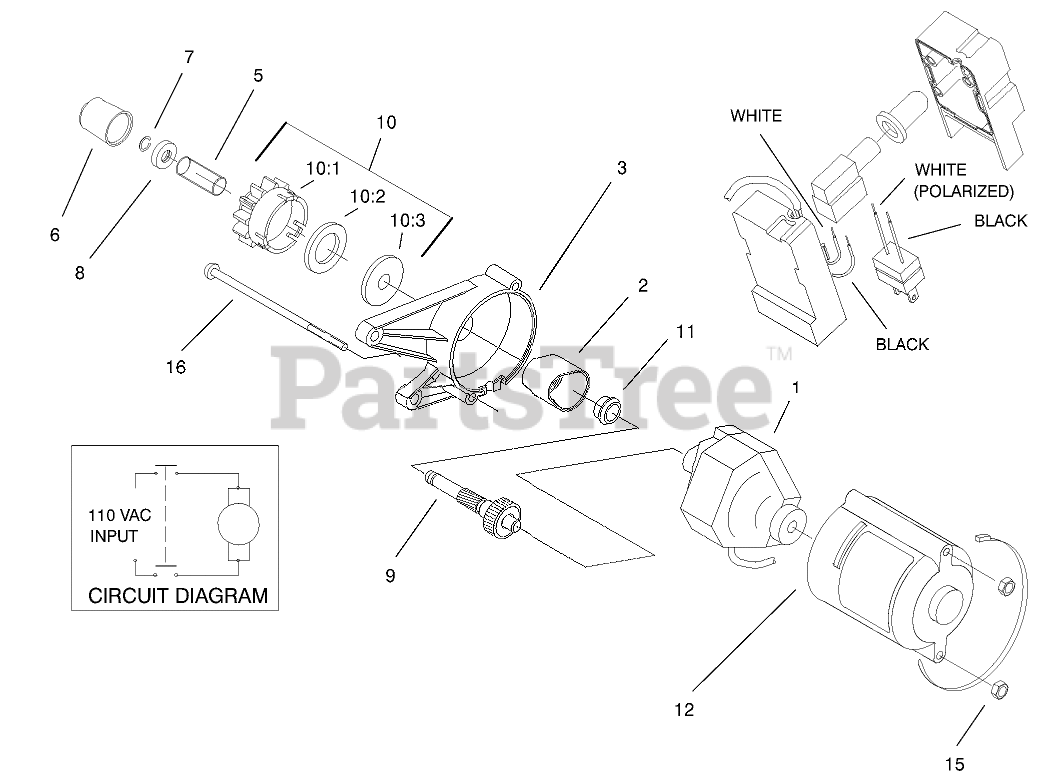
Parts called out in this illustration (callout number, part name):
1	STARTER MOTOR ASM
2	COVER-GEAR
3	HOUSING-UPPER, STARTER
5	SPRING
6	CAP-PINION
7	RING-LOCK
8	STOP-PINION
9	SHAFT/GEAR ASM
10	PINION ASM
10:2	PINION
10:3	RING-RUBBER
11	BUSHING
12	HOUSING-LOWER, STARTER
15	NUT-LOCK, NI
